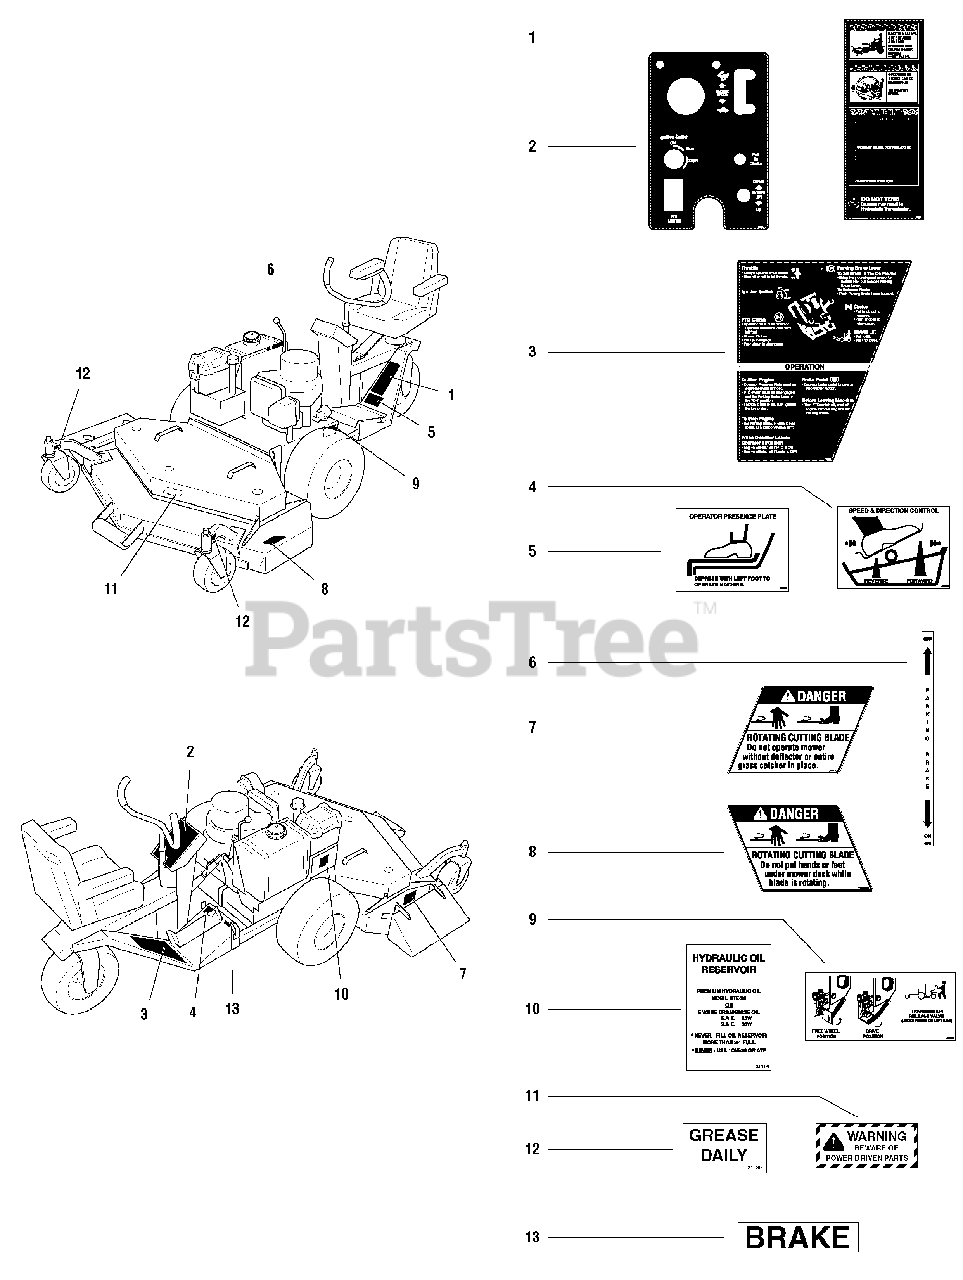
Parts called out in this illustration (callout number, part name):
1	DECAL, Danger/Warning
2	DECAL, Instrument Panel
3	DECAL, Operation
4	DECAL, Speed/Direction Control
5	DECAL, Operator Presence
6	DECAL, Parking Brake
7	DECAL, Danger (Chute In Place)
8	DECAL, Danger (Hand Under Deck)
9	DECAL, Transmission Release
10	DECAL, Hydro Reservoir
11	DECAL, Warning (located under guard)
12	DECAL, Grease Daily
13	DECAL, Brake
14	DECAL, OPEI (Not serviced)
15	ID Tags (Not serviced)
